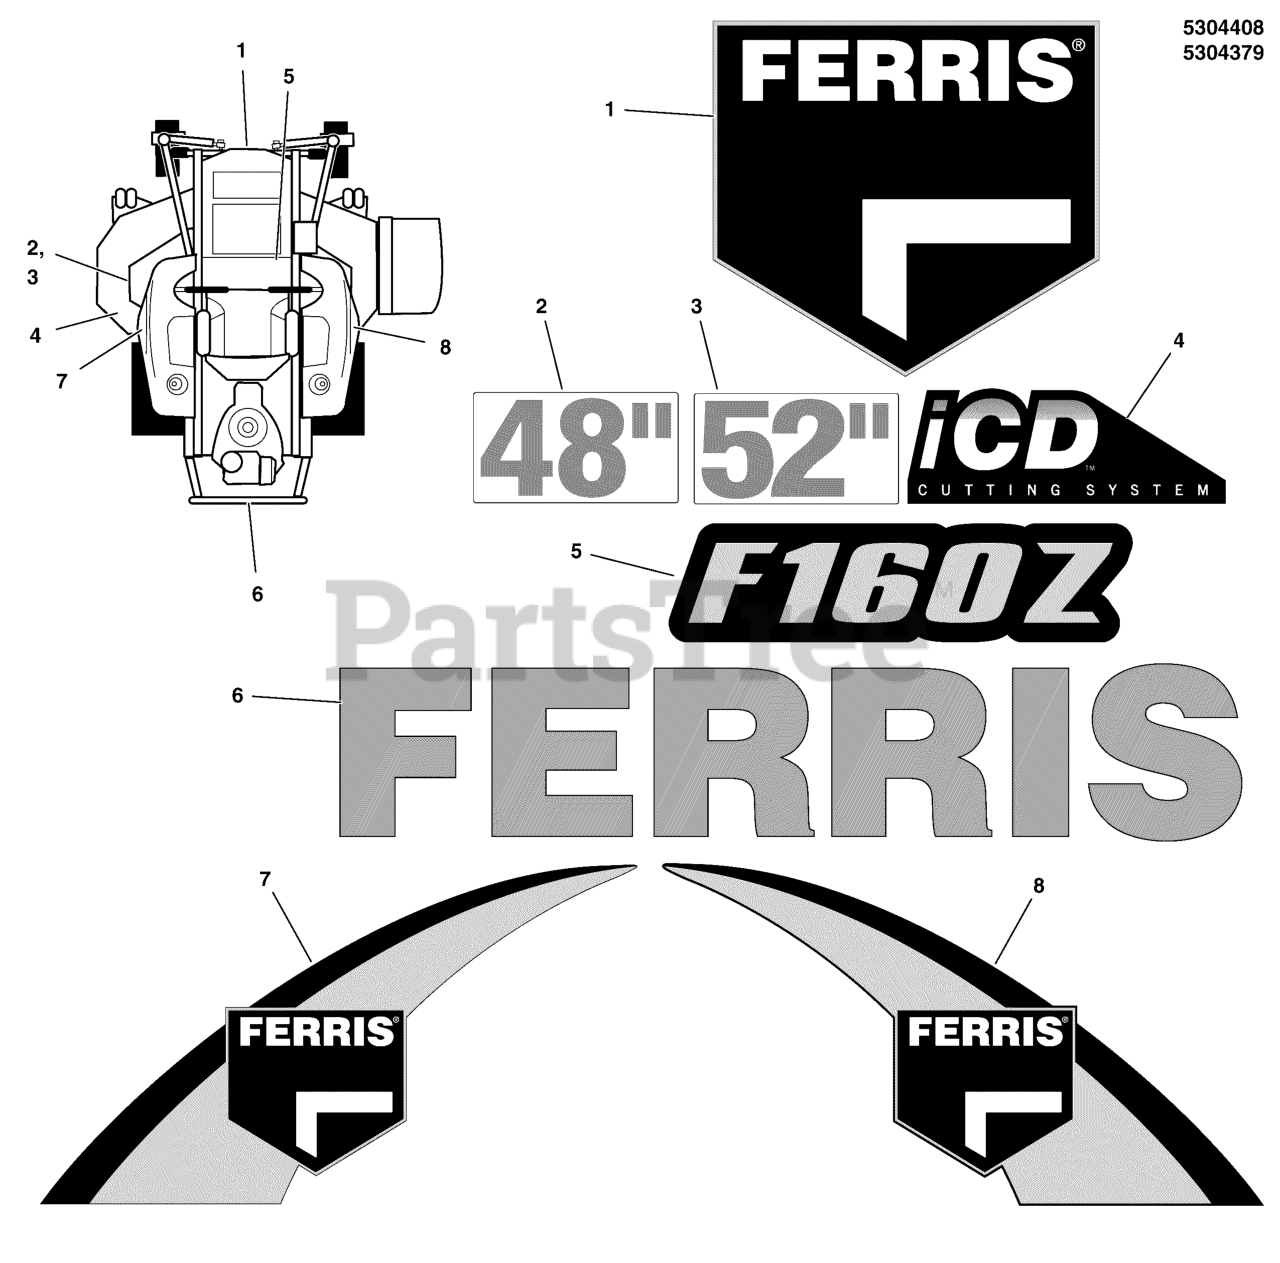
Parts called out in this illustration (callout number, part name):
1	DECAL, FERRIS LOGO, MEDIUM
2	DECAL, 48
3	DECAL, 52
4	DECAL, iCD CUTTING SYSTEM
5	DECAL, MODEL, F160Z
6	DECAL, FERRIS, 2.23" X 11.39"
7	DECAL, Model, Left Hand
8	DECAL, MODEL, RIGHT HAND
